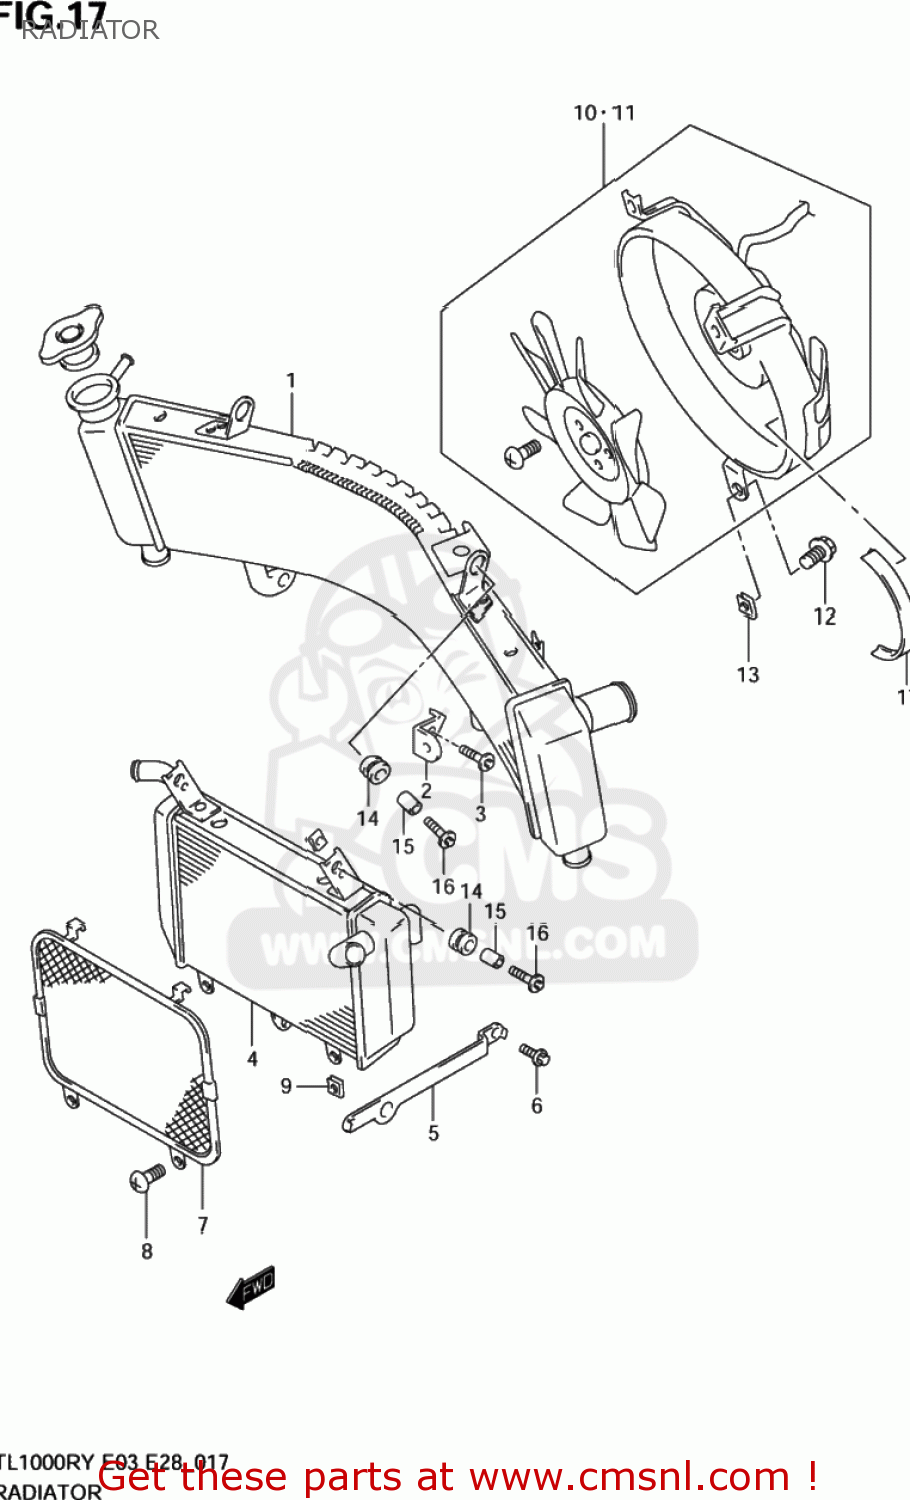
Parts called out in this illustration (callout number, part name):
1	RADIATOR ASSY,
2	BRACKET,RADIATOR UPR
3	BOLT
4	RADIATOR ASSY,WATER LWR
5	BRACKET,RADIATOR LWR
6	BOLT
7	COVER,RADIATOR
8	SCREW 6X12
9	NUT
10	FAN ASSY,RADIATOR,R
11	FAN ASSY,RADIATOR,L
12	BOLT
13	NUT
14	CUSHION
15	SPACER(6.5X10X12)
16	BOLT(6X25)
17	MOLDING,FAN SHROUD,L,L(L:165)
